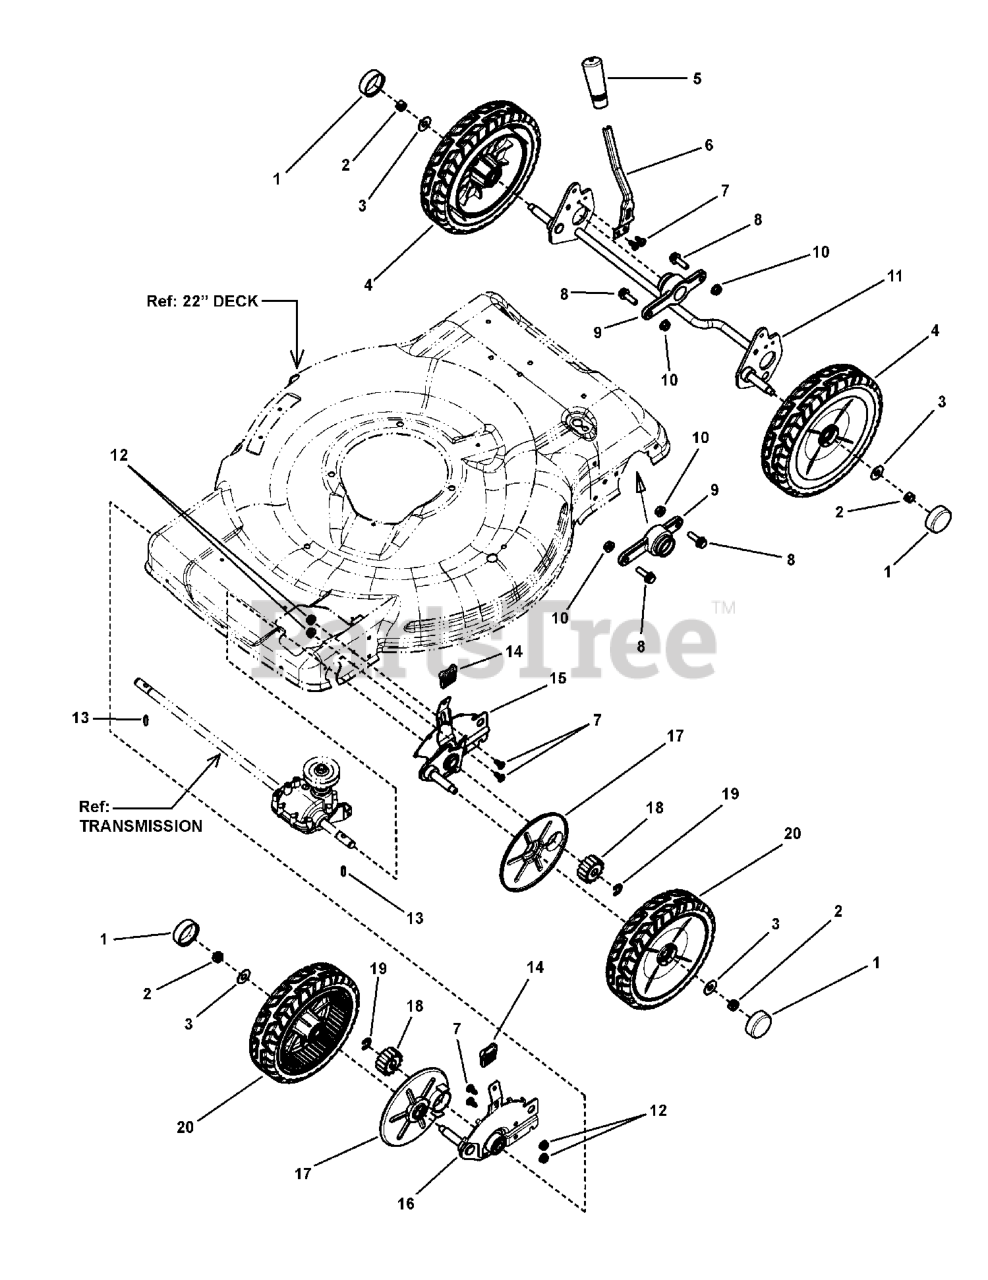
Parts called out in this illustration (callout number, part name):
1	HUBCAP, ROUND, JD YELLOW
2	HCLN - JAM - 3/8-16 YZ
3	WASHER, FLAT, 1" OD X .387 ID
4	ASSY, WHEEL, W/BEARING 9" JD TRD, D YELLOW
5	GRIP HOC
6	LEVER, SPRING, HOC
7	TORX ST, 1/4-20 X .550
8	HFLB, 5/16-18 X 1 YZ
9	HOLDER, BEARING, RWD
10	FLN, 5/16-18 YZ
11	WELDMENT, REAR CROSSBAR, RWD
12	HFLN, 1/4 X 20 YZ
13	PIN, DRIVE, 22" WBM FWD
14	GRIP, HT LATCH, BLACK
15	ASSY, HOC, LF, 22" WBM, PROPELLED
16	ASSY, HOC, RF, 22" WBM, PROPELLED
17	SHIELD, DUST, 22" WBM, FWD
18	GEAR, PINION, 22" WBM, FWD
19	RETAINING RING
20	ASSY, WHEEL, 8X2 DRIVE JD TREAD, BB, JD YELLOW
